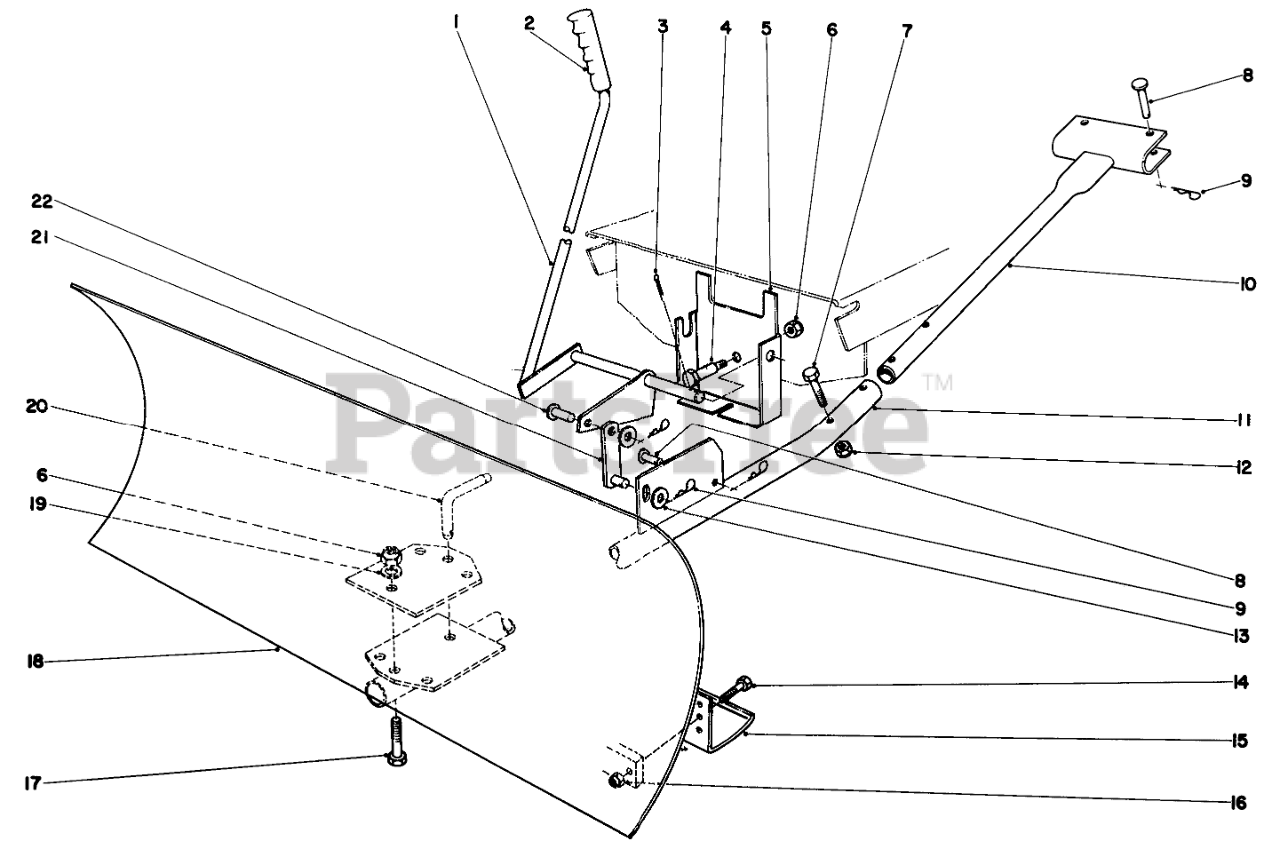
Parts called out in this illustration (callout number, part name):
1	Lift Shaft Assembly
2	Handle Grip
3	PIN-COTTER
4	Shoulder Bolt
5	Bracket
6	1/2-13 CONELOCK NUT
7	SCREW-HH
8	PIN-CLEVIS
9	PIN-COTTER, HAIR
10	Connecting Rod
11	Snow Blade Tongue Assembly
12	NUT-LOCK, CONE
13	WASHER-FLAT
14	SCREW-HH
16	NUT-LOCK, CONE
17	SCREW-HH
18	Blade
19	WASHER-LOCK
20	Pivot Pin
21	Link Assembly
